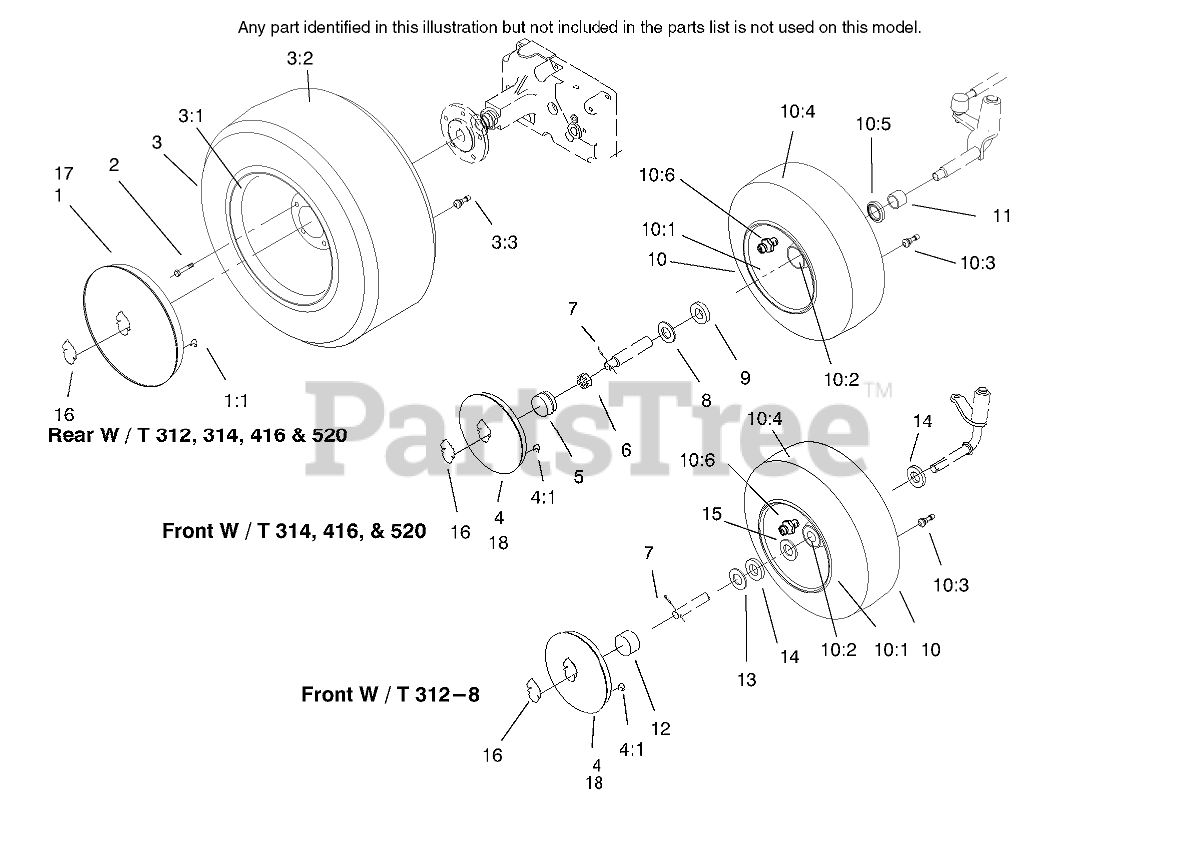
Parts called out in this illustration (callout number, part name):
2	BOLT-LUG
3	ASM-Wheel & Tire
3:1	WHEEL
3:2	TIRE
3:3	VALVE
7	PIN-COTTER
10	FRONT WHEEL ASM
10:1	Wheel ASM
10:2	BEARING-WHEEL
10:3	VALVE
10:4	Tire (16 x 6.5-8) 2-Ply -2 Wheel Axel
10:6	ZERK-GREASE
12	HUBCAP
13	WASHER WHEEL
14	WASHER
15	WASHER-SHIM
